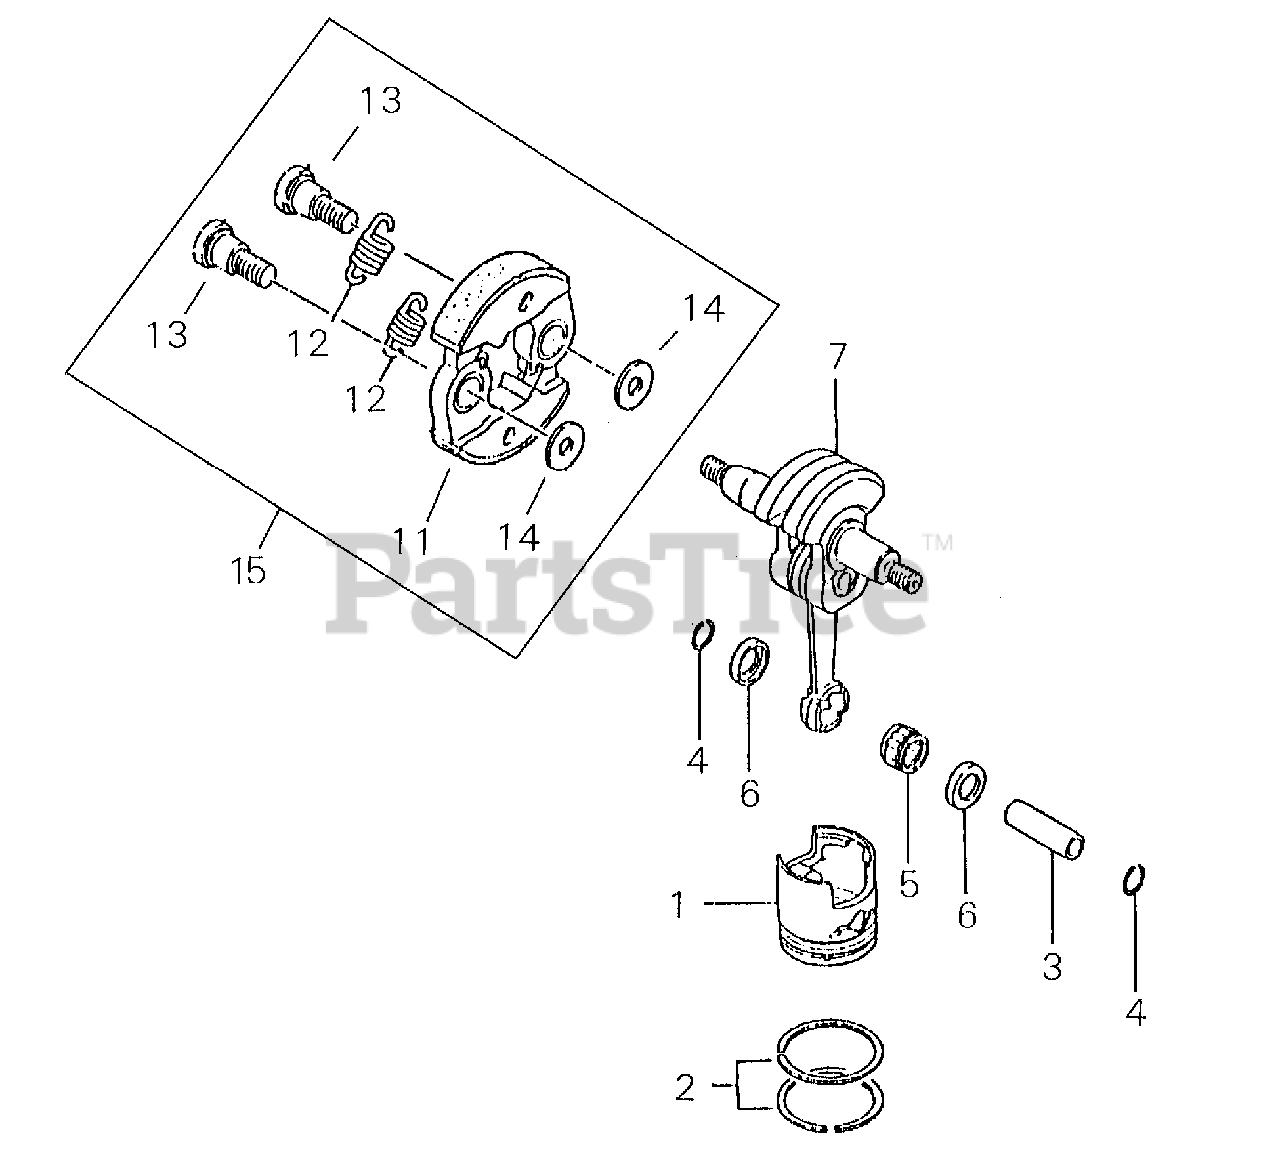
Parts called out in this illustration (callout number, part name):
1	PISTON
2	RING, PISTON
3	PIN, PISTON
4	RING, RETAINING
5	BEARING, NEEDLE
6	WASHER, THRUST
7	CRANKSHAFT ASSY
11	SHOE, CLUTCH
12	SPRING, CLUTCH
13	BOLT, CLUTCH
14	WASHER
15	CLUTCH ASSY
